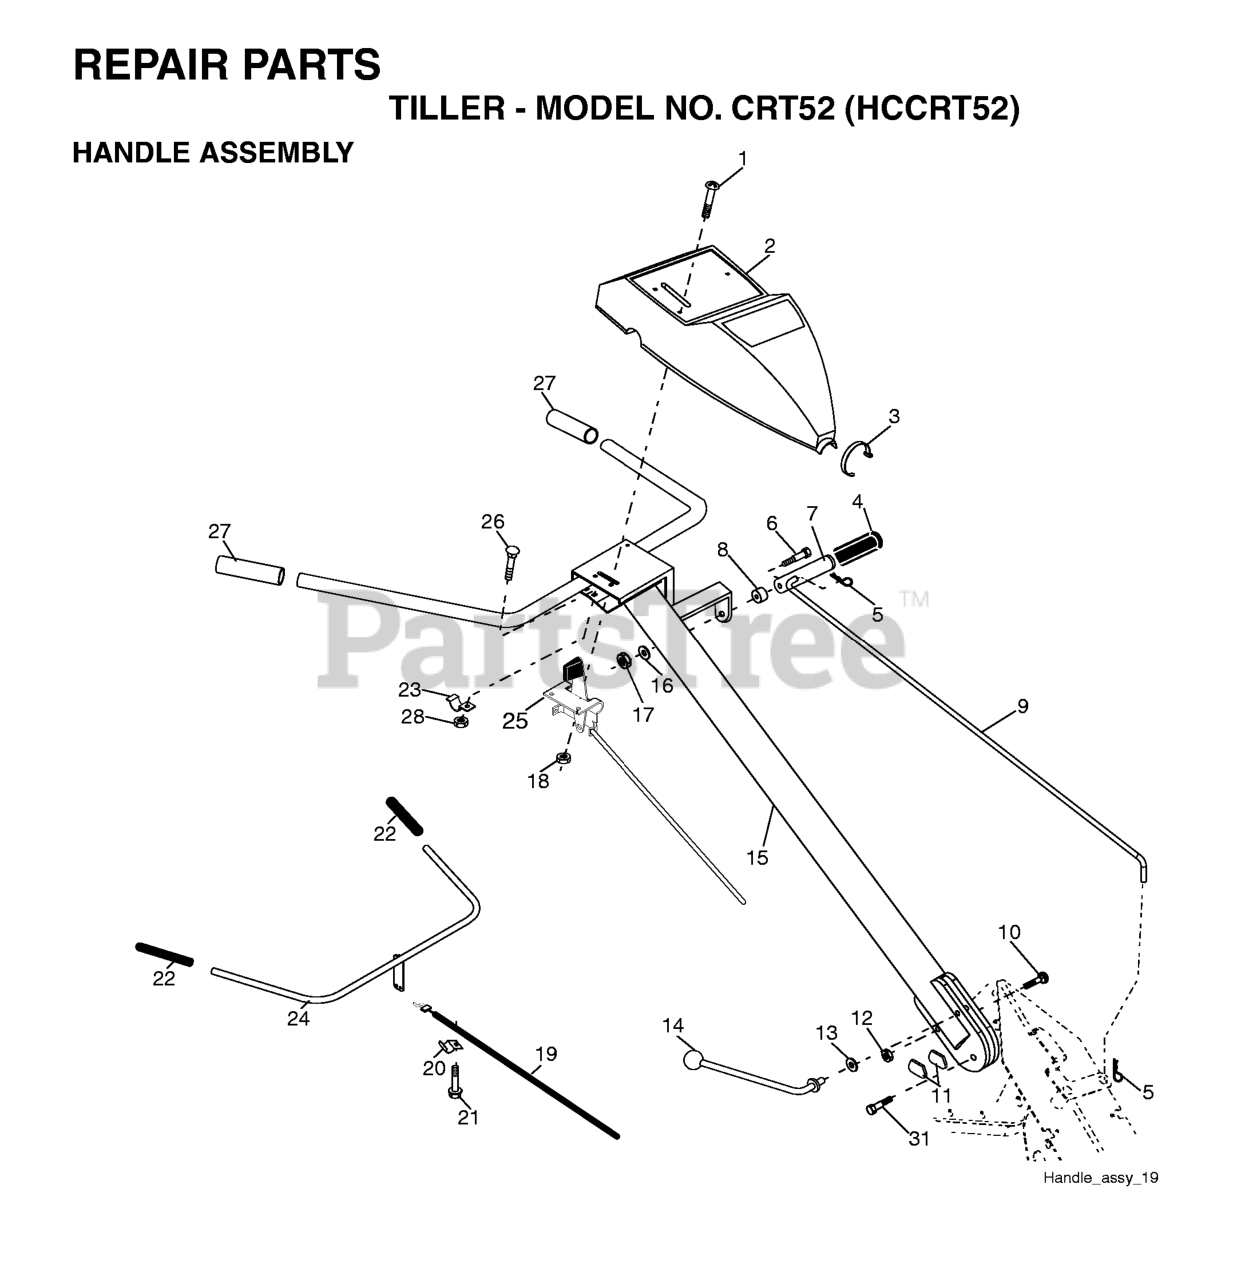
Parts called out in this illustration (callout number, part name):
1	SCREW.PNHD.10-24
3	TIE CABLE CRT
4	GRIP T
5	RETAINER M
6	SHOULDER BOLT ST
7	SHIFT HANDLE CRT
8	GROMMET.RUBBER.CRT.TILLER
9	SHIFT ROD CRT
10	BOLT D
11	LOCK.HANDLE.CRT
12	LOCKNUT
13	WASHER CRT
14	LEVER.LOCK.CRT
15	HANDLE
16	LOCKWASHER
17	NUT
18	NUT **
19	CABLE, CLUTCH 48 "Z"
20	CONDUIT.CLIP.PLATED
21	TAPPING SCREW
22	GRIP BAR CRT(1)
23	CLAMP.BAR.CRT.BLACK
24	BAR ASSY CONTROL
25	CONT,THROTTLE
27	KIT.GRIP.HANDLE.5.00.BLK.VINYL
28	NUT
31	BOLT.PIVOT
